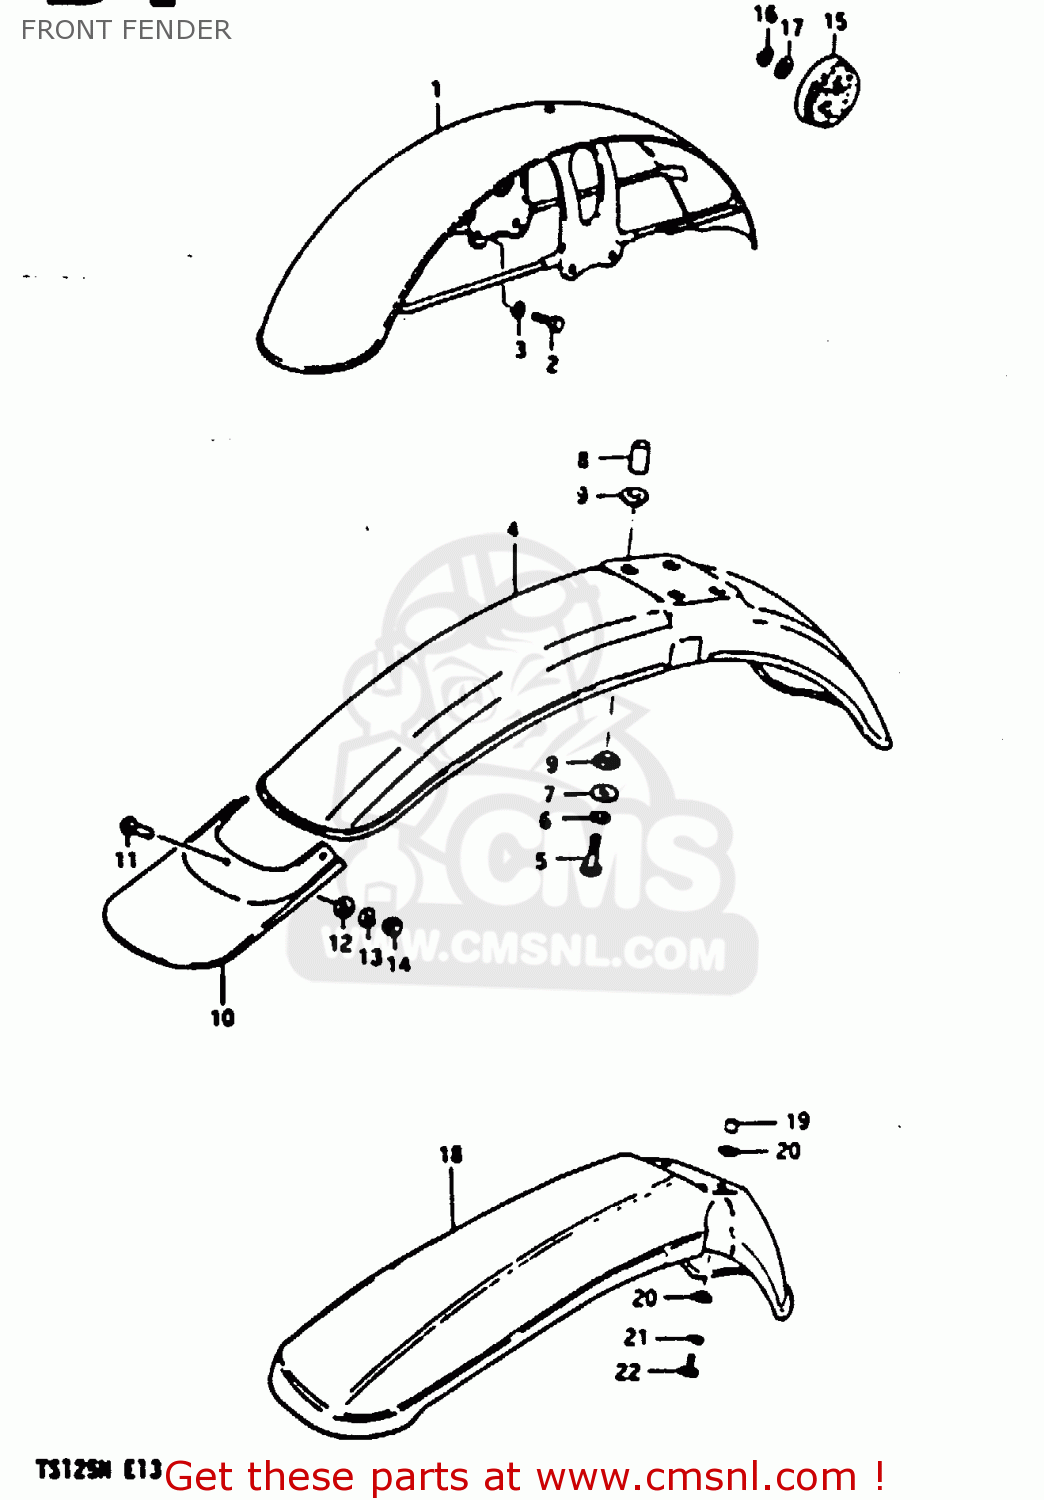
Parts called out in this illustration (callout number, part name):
1	FENDER,FRONT
2	BOLT
3	LOCK WASHER
4	FENDER,FRONT
5	BOLT
6	LOCK WASHER
7	WASHER
8	SPACER (6.8X10X20)
9	SPACER
10	MUD FLAP,FRONT FENDER
11	SCREW
12	WASHER
13	LOCK WASHER
14	NUT
15	REFLEX REFLECTOR,FR
16	LOCK WASHER
17	WASHER
18	18-2
19	20
20	21
21	22
